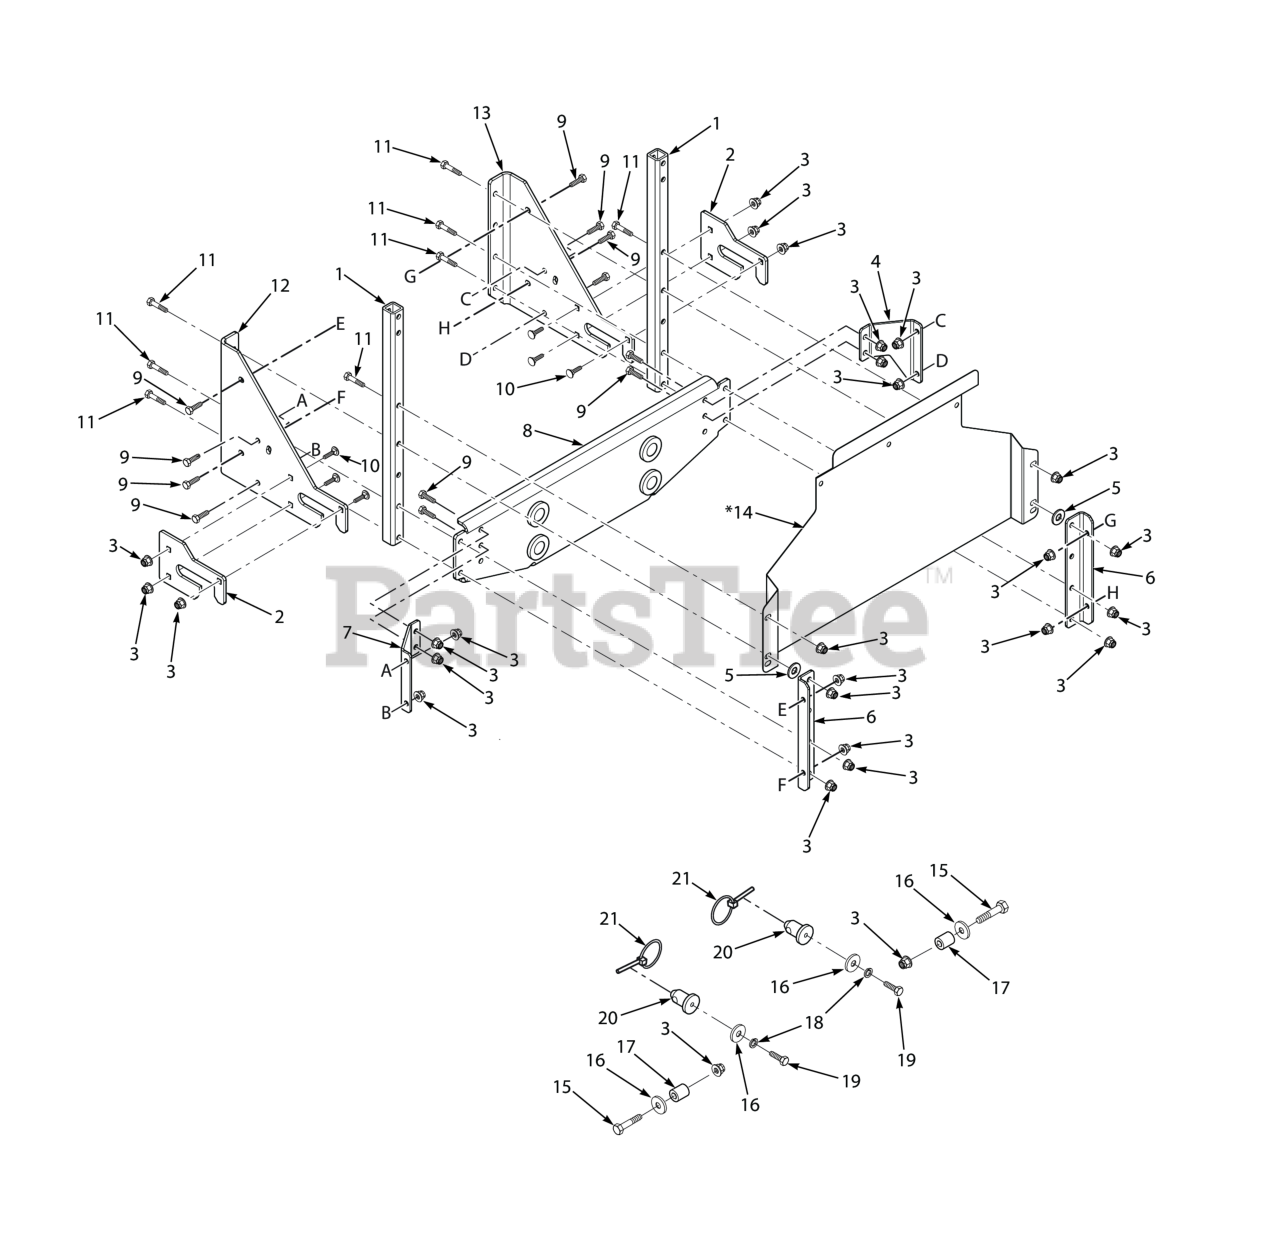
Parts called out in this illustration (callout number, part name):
1	Tube, Upright
2	Wear Plate, GC
3	Nut, Flange Elastic Stop Nut, 3/8-16
4	Angle Brace, LH GC
5	Flatwasher, 7/16-.469 x 1.75 x .25 (48, 52)
6	Mounting Bracket, GC Tube
7	Angle Brace, RH GC
8	Mounting Bracket Weldment
9	Bolt, Hex Head 3/8-16 x 1"
10	Carriage Bolt, 3/8-16 x 1.0"
11	Capscrew, Hex Head 3/8-16 x 2-1/2"
12	RH Mounting Bracket, GC
13	LH Mounting Bracket, GC
14	Heatshield (used on STT & STTII Models Only)
15	Bolt, Hex Head 3/8-16 x 2-1/4" - 61"
16	Flatwasher, 3/8-.406 x 1-1-1/2 x 7 Gauge
17	Spacer
18	Lockwasher, 3/8" Spring, Kawasaki FX / FT & FT-EFI / B&S 32BV
19	Bolt, Hex Head 3/8-16 x 1-1/4", Kawasaki FX / FT & FT-EFI
20	Pin, GC Locator
21	Quick Pin, 5/16" Dia.
